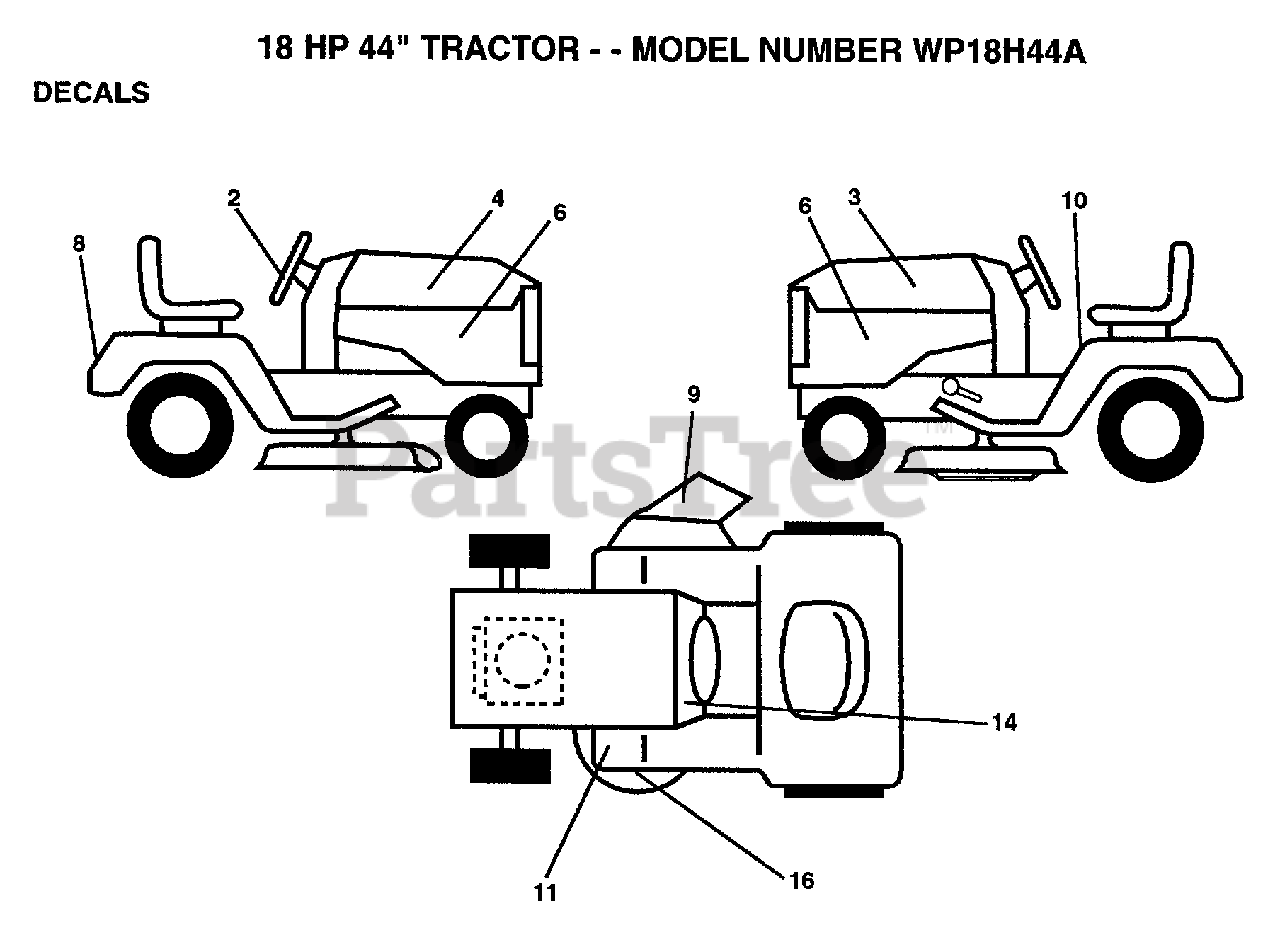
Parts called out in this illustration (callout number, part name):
2	DECAL, INSERT
3	DECAL.HOOD.LH
4	DECAL.HOOD.RH
8	DECAL, LOGO, FENDER
9	DECAL WARING
10	DECAL
16	DECAL INSTRUCTION CAUTION
